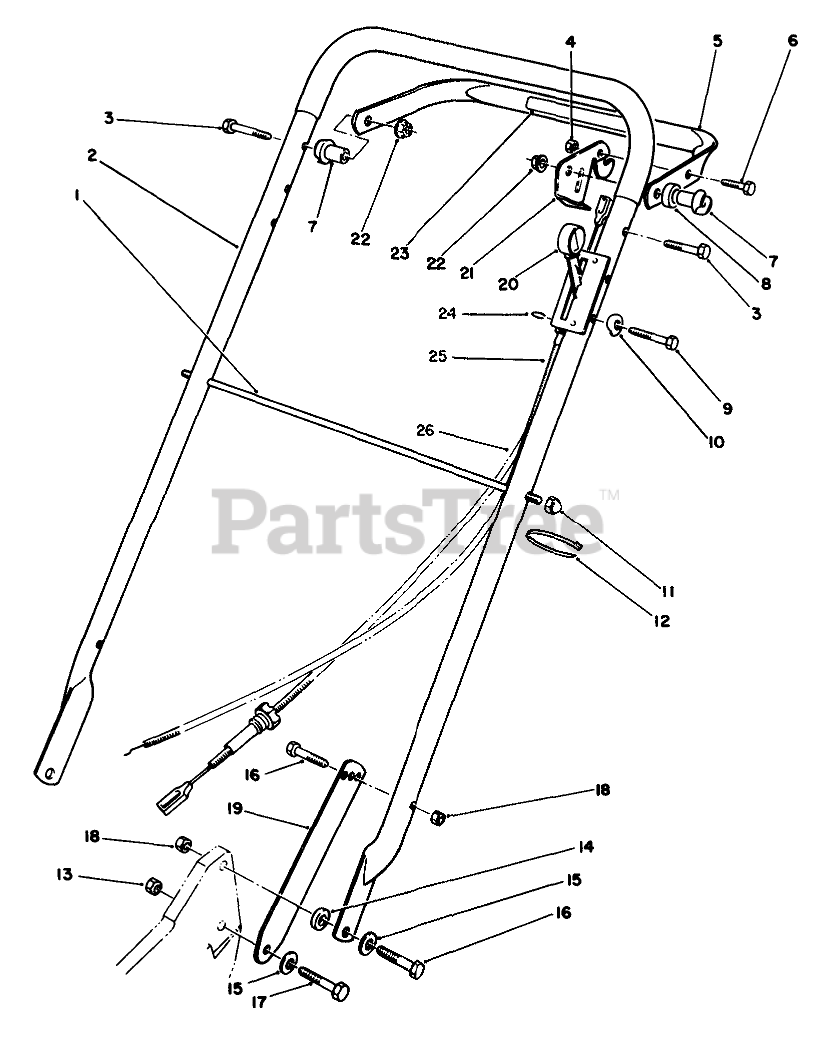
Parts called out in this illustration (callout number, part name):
1	ROD-SUPPORT, BAG
2	Handle
3	SCREW-HH
4	NUT-LOCK, NI
5	Bar-Control
6	SCREW-HH
7	SPACER-SUPPORT
8	SPACER-NYLON
9	SCREW-HH
10	WASHER
11	NUT-CAP
12	TIE-CABLE
13	NUT-LOCK, NI
14	SPACER-PIN, MOUNTING
15	WASHER-BELLEVILLE
16	SCREW-HH
17	SCREW-HH
18	NUT-LOCK, NI
19	HANDLE LATCH
20	Bracket Throttle
21	LEVER-CONTROL
22	NUT-HF
23	DECAL - INT'L TRACTION
24	E-RING
25	CABLE, THROTTLE, OHV
26	TRACTION CABLE
